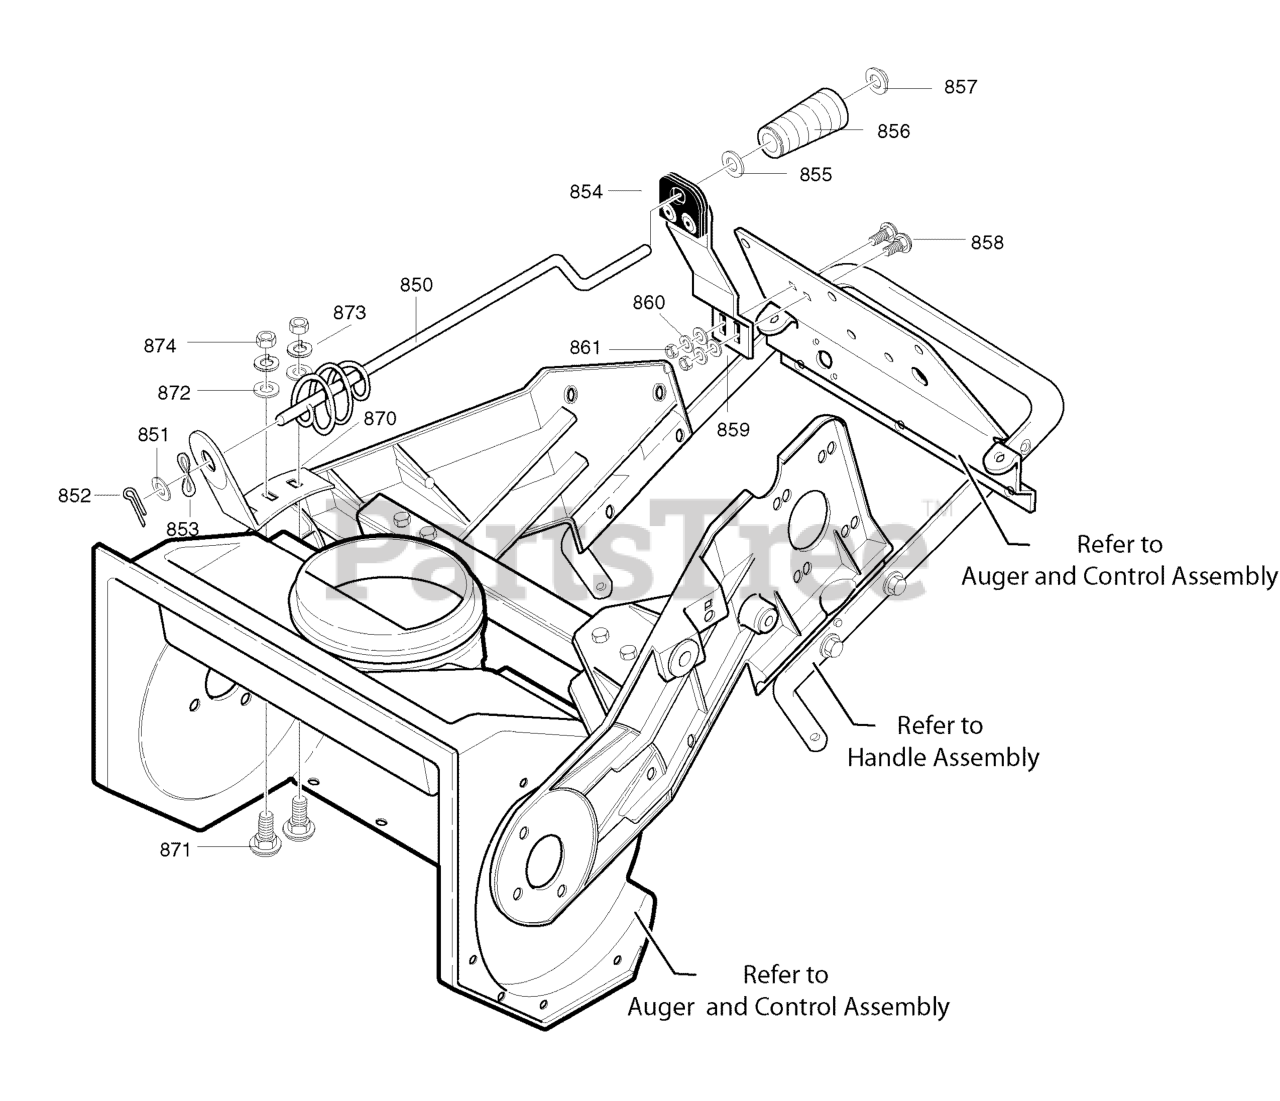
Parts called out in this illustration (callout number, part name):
850	ROD, CHUTE
851	WASHER, Flat, 13/32
852	PIN, COTTER
853	WASHER, CURVED SPRING
854	ASSY, CHUTE CRANK BRACKET
855	WASHER, Flat, 13/32
856	KNOB, SLEEVE
857	NUT, PUSH
858	BOLT, 1/4-20 X .63 CARRIAGE
859	WASHER, FLAT .349 X .69 X .065
860	WASHER, SPLIT LOCK .31 X .58 X .08
861	NUT, 1/4-20 HEX
870	BRKT, CHUTE ROTATE
871	BOLT, 5/16-18 X .75 CARRIAGE
872	WASHER, FLAT .349 X .69 X .065
873	WASHER, SPLIT LOCK .31 X .58 X .08
874	NUT, 5/16-18 HEX
